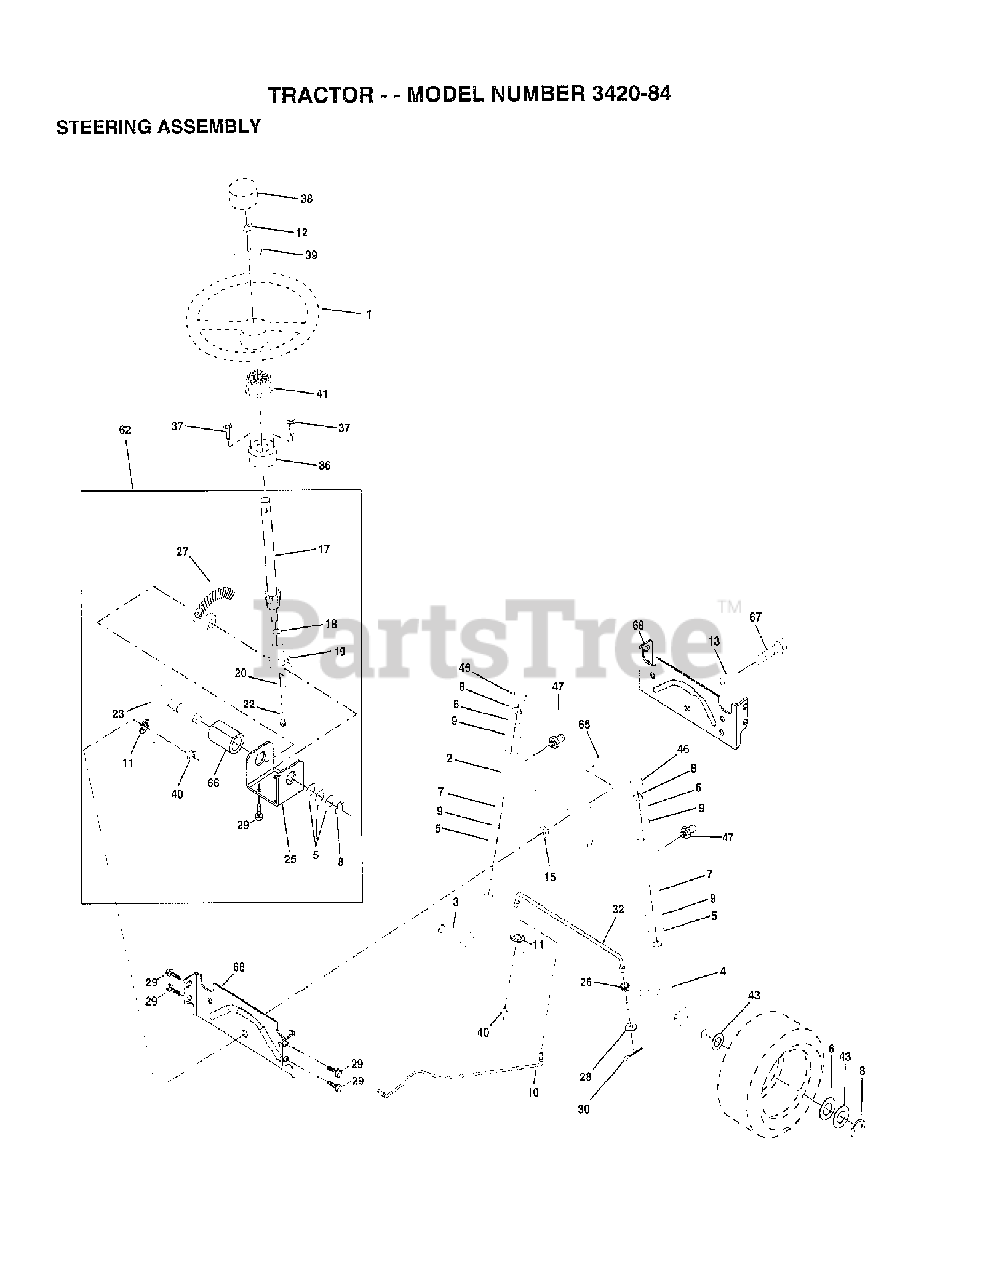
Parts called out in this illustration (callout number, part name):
1	Steering Wheel
2	Half Axle Assembly, Welded
3	SPINDLE.ASM.LH
4	SPINDLE ASM RH
8	RING CLIP
9	BEARING.STEERING.COLUMN
10	DRAGLINK-STAMPED
11	WASHER, LOCK 3/8
12	NUT.HEX.1/2-20
13	BEARING AXLE
15	LOCK NUT
17	STEERING SHAFT
18	THRUST WASHER
19	SHAFT,SUPPORT
20	WASHER
23	SHAFT,PITMAN
25	BRACKET STEERING
26	BUSHING STEERING
27	GEAR.SECTOR
28	WASHER
30	COTTER PIN
36	BUSHING STRG 3/4
37	SCREW.TT.#10-32X.5.3/8.FLANGE
38	INSERT STR WHL
40	NUT
46	CAP.SPINDLE.BLACK
47	ZERK.GREASE.TAPERED
62	STEERING KIT
65	SPACER AXLE
66	BEARING ARM
67	BOLT.HEX.FINISHED.5/8
68	AXLE, BRACE
